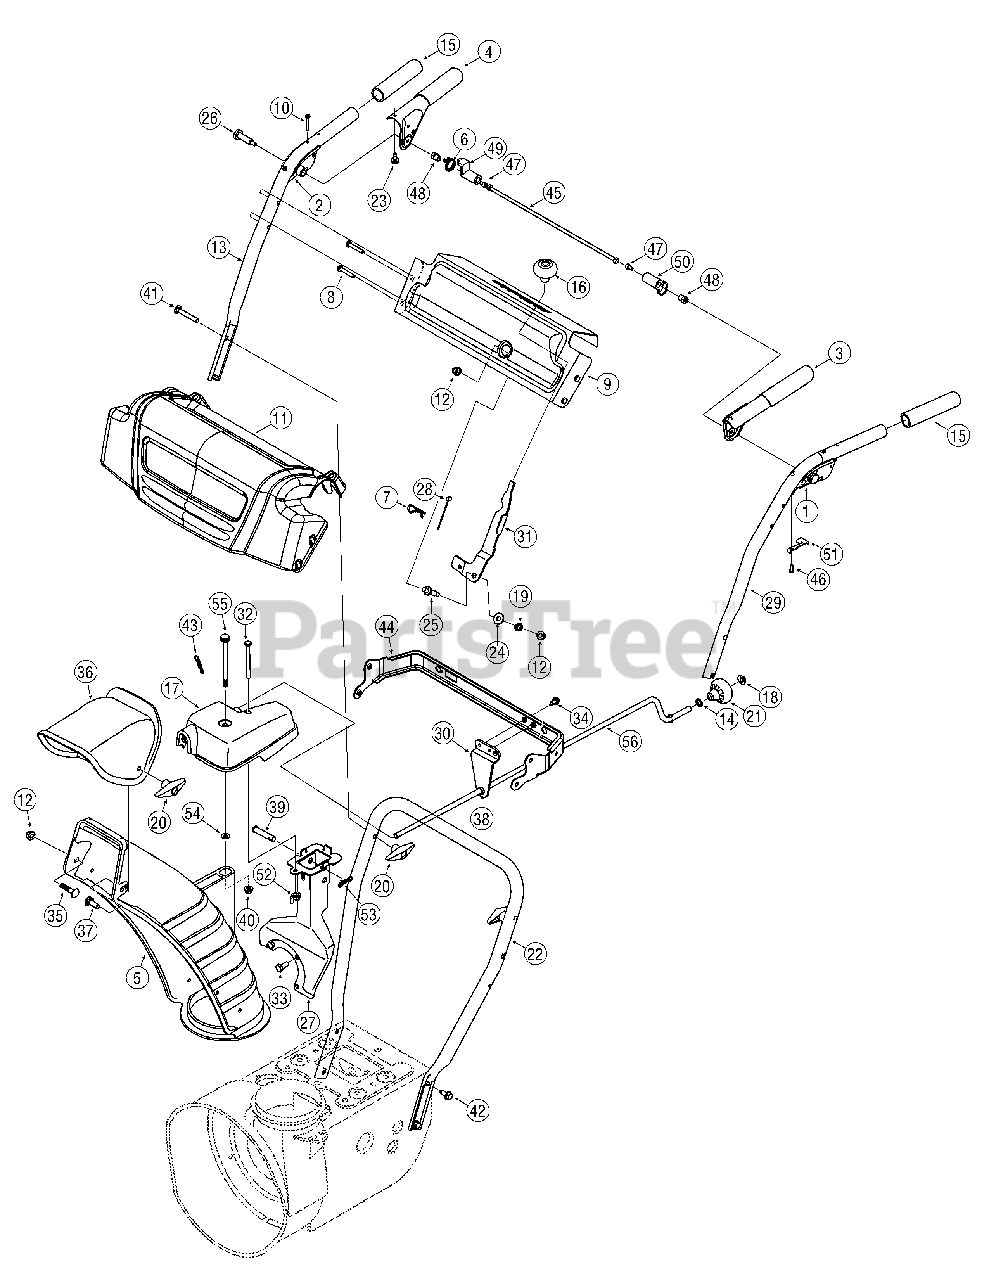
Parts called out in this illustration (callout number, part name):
1	Handle Assembly, Clutch Lock, LH
2	Handle Assembly, Clutch Lock, RH
3	Handle Ass’y, Engage, LH
4	Handle Ass’y, Engage, RH
5	Chute, Lower
6	Spring, Torsion, .8156 ID x .3038
7	Click Pin
8	Screw, 1/4-20 x 1.625
9	Panel, Handle, (no cutout)
10	Screw, Machine, #10-24, 1.375
11	Handle Panel Cover
12	Nut, Flange Lock, 5/16-18, Nylon
13	Handle, Upper, RH
14	Washer, Flat, .375 x .738 x .063
15	Grip, 1.0 ID x 5.0
16	Knob, Shift, Black
17	Gearbox Assembly
18	Cap, Push, 3/8 Rod
19	Spring, .39 x .60 x .88
20	Knob, 5/16-18, Black
21	Crank Knob
22	Handle, Lower
23	Bumper, Rubber, .62 OD x .22
24	Washer, Flat, .385 x .870 x .092
25	Bolt, Shoulder, 5/16-18 x 0.905
26	Screw, Shoulder, .43 x 1.3, 1/4-20
27	Bracket, Chute Support
28	Cable, Speed Selector
29	Handle, Upper, LH
31	Shift Lever
32	Screw, 1/4-20 x 3.00
33	Screw, 5/16-24 x .750
34	Bolt, Carriage, 5/16-18, 1.0
35	Bolt, Carriage, 5/16-18, .750
36	Chute, Upper, w/ Label
37	Screw, 1/4-20 x .625
38	Bushing, Plastic, .380
39	Pin, Clevis
40	Nut, Flange Lock, 1/4-20
41	Screw, Carriage, 5/16-18, 2.25
42	Screw, 5/16-18, 2.25, Gr5
43	Pin, Cotter
44	Bracket, Panel
45	Rod, Pivot
46	Screw, #8-16 x .50
47	Screw, 1/4-20 x .50
48	Nut, Hex, 1/4-20
49	Plate, Lock
50	Cam, Clutch Lock
51	Spring, Clutch Lock
52	Nut, Wing
53	Bow-Tie Cotter Pin
54	Washer, Flat, .25 x .630 x .0515
55	Scr. Shldr. Flg., .312 x 3.5 x 1/4-20
56	Crank, Chute
